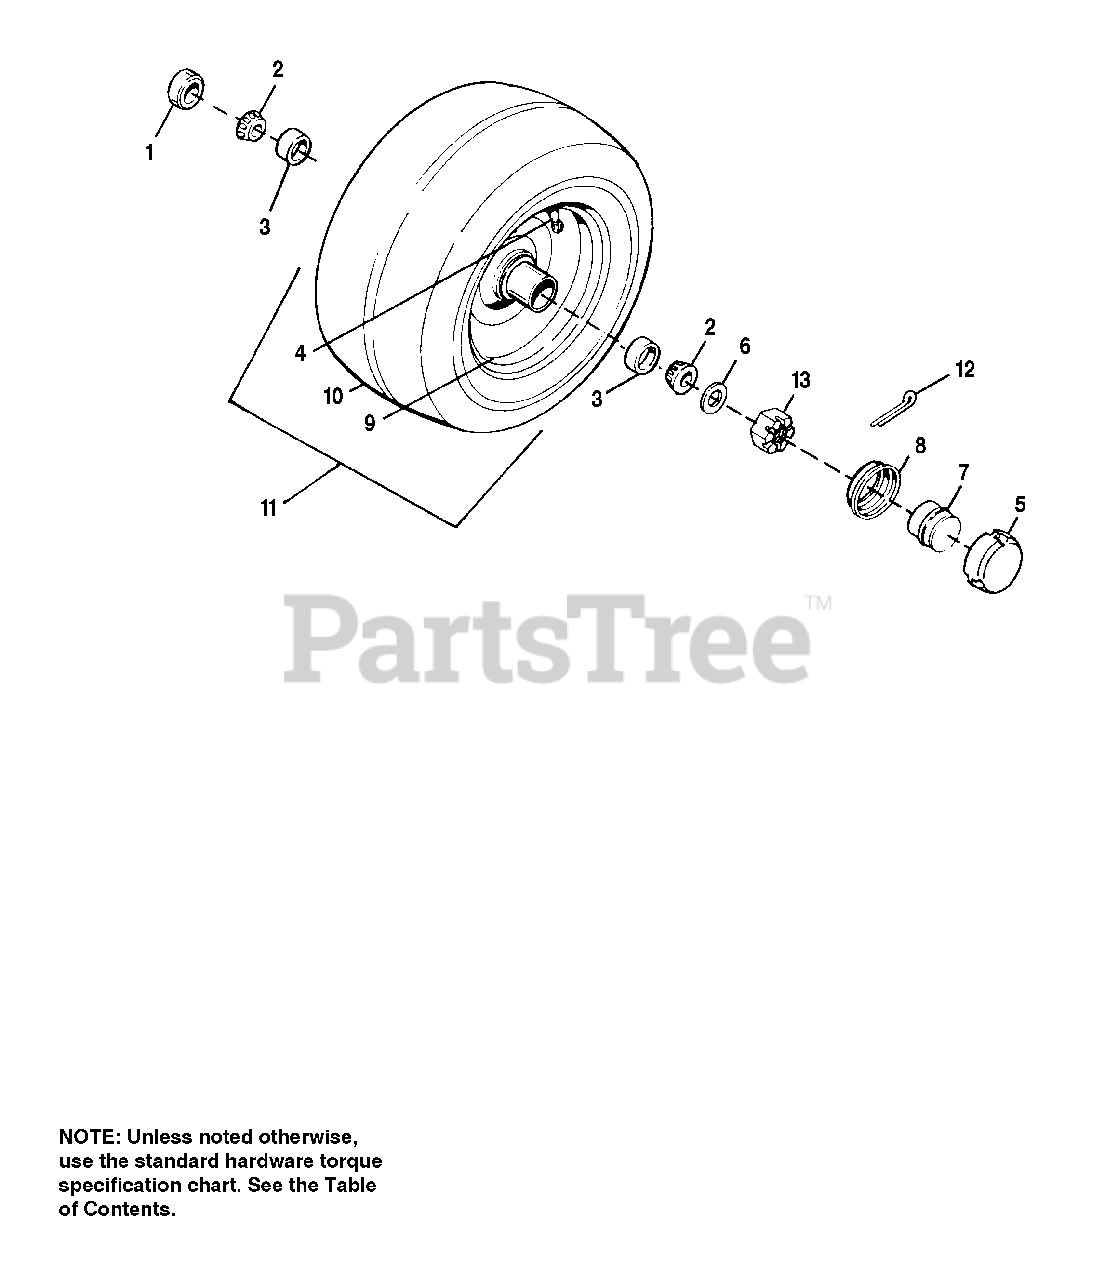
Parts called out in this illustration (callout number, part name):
2	BEARING, Cone
3	BEARING, Cup, Wheels
4	VALVE STEM & CAP
7	CAP, Hub, Cover
8	RETAINER, Hub Cap
9	FRONT WHEEL ASSY., Metallic Gray, 16 x 7.50-8
10	TIRE, Multi-Trac, 16 x 7.50-8 (Dico)
10	TIRE, Turf Trak, 16 x 7-50-8 (Dico)
11	FRONT WHEEL & TIRE ASSY., Metallic Gray, 16 x 7.50-8
12	PIN, Cotter, 1/8 x 1 3/4
13	NUT, Hex, Slotted Hd., 3/4-16
